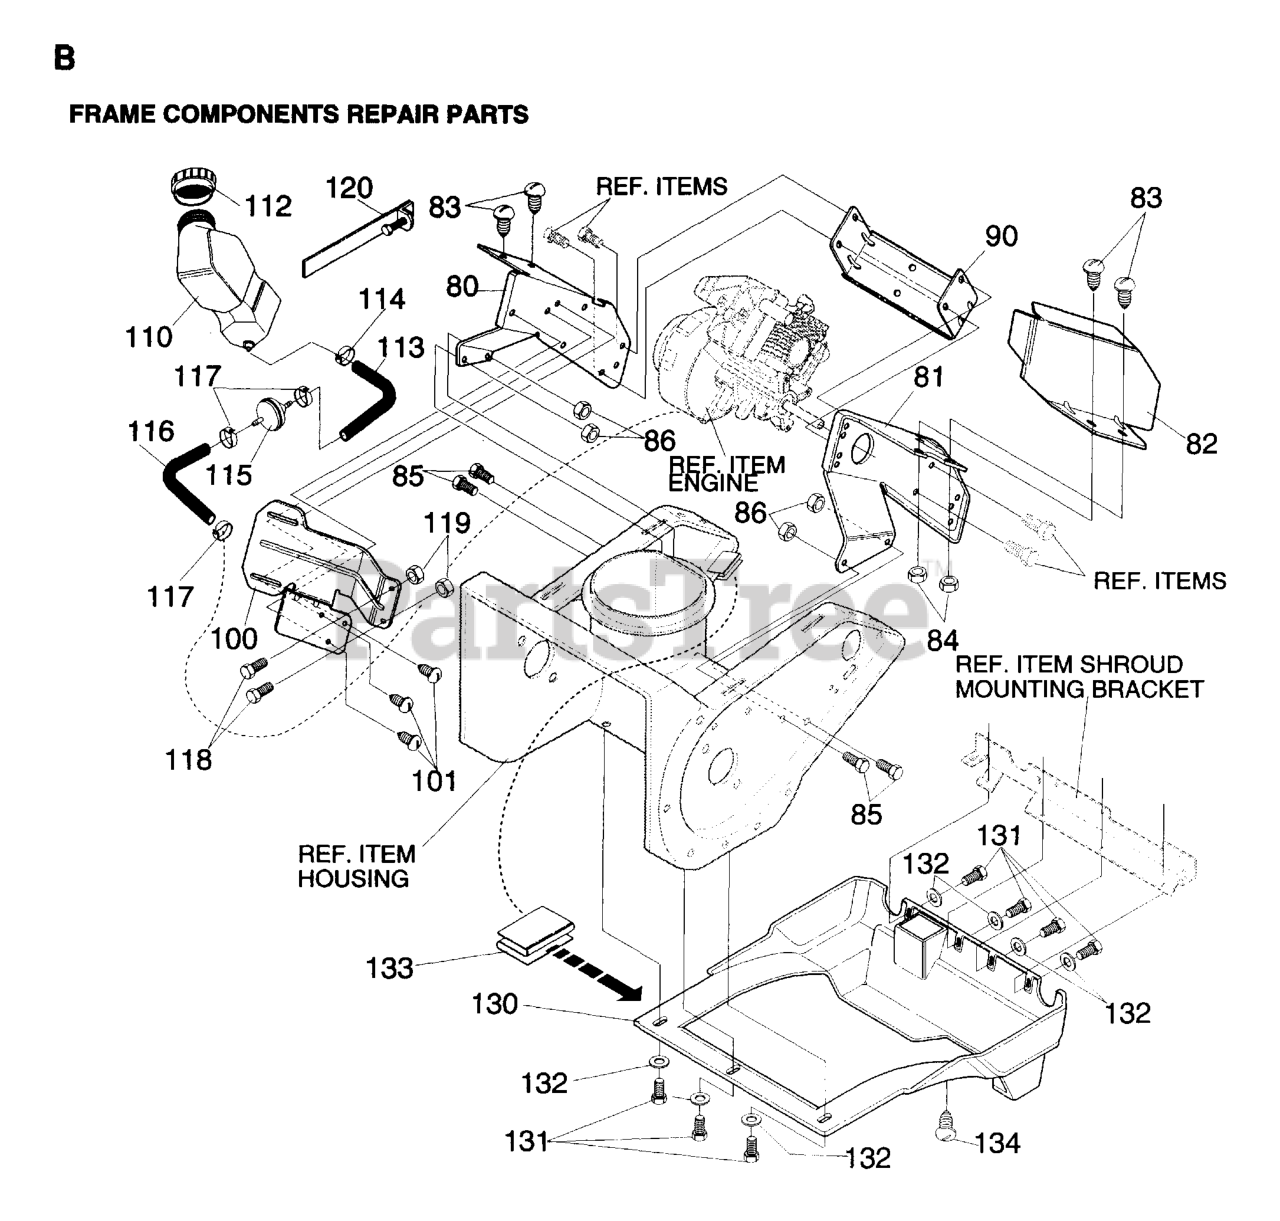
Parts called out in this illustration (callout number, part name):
83	BOLT
84	NUT
86	LOCKNUT
